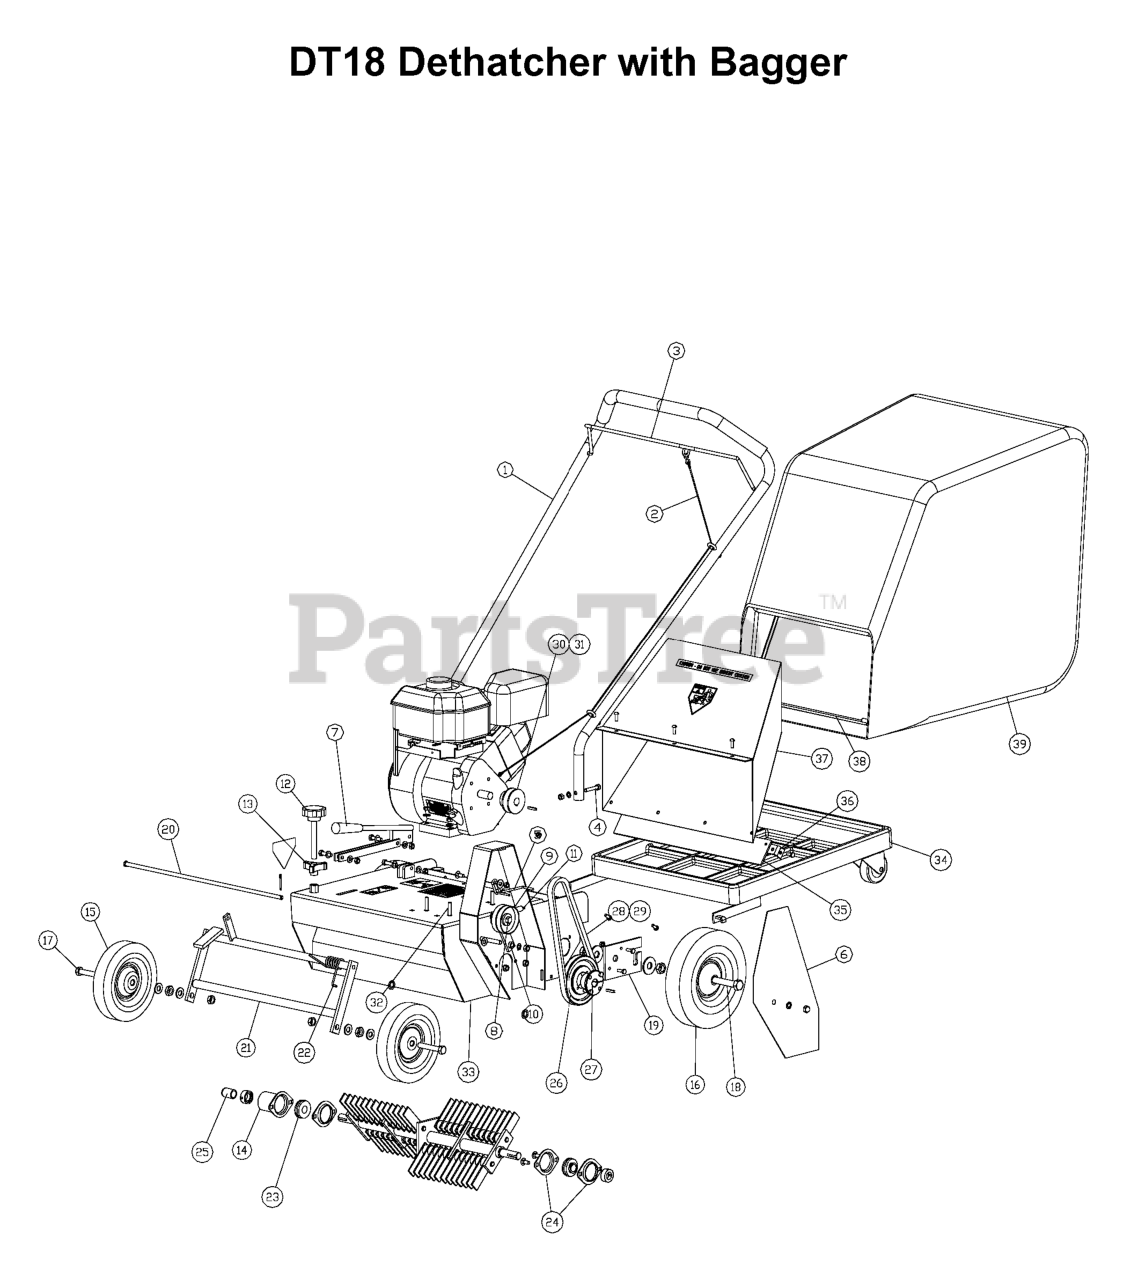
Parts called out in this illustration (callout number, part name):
1	HANDLE ASSY
2	CLUTCH CABLE
4	BOLT KIT
5	BELT KEEPER KIT
6	BELT GUARD KIT ORN
7	DEPTH LEVER ASSY
8	IDLER ASSY KIT
9	PULLEY
10	MTG ARM, IDLER PULLEY
11	SPRING
12	DEPTH ADJUSTMENT KNOB
13	3-PRONGED LOCK DEPTH
14	ROTOR GUARD
15	WHEEL
16	BOLT KIT
17	KIT, WHEEL
18	KIT, WHEEL, RIGHT REAR
19	LIFT ARM ROD KIT
20	LIFT ARM ASSY OR
21	TORSION SPRING
22	BEARING
23	STAMPING KIT
24	ROTOR CAP
26	STAMPING KIT
27	V-PULLEY
28	BUSHING KIT
29	V-BELT
30	V-BELT
31	V-PULLEY
32	V-PULLEY
33	ENGINE BOLT KIT
35	DEFLECTOR KIT
36	DEFLECTOR, NEOPRENE
37	KIT, HOPPER LID
38	DIAL GAUGE KIT
39	KIT, PUSH-PULL CONTROL
40	SEED HOPPER
41	AGITATOR BAR
44	Kit Decal SD18 Seeder
